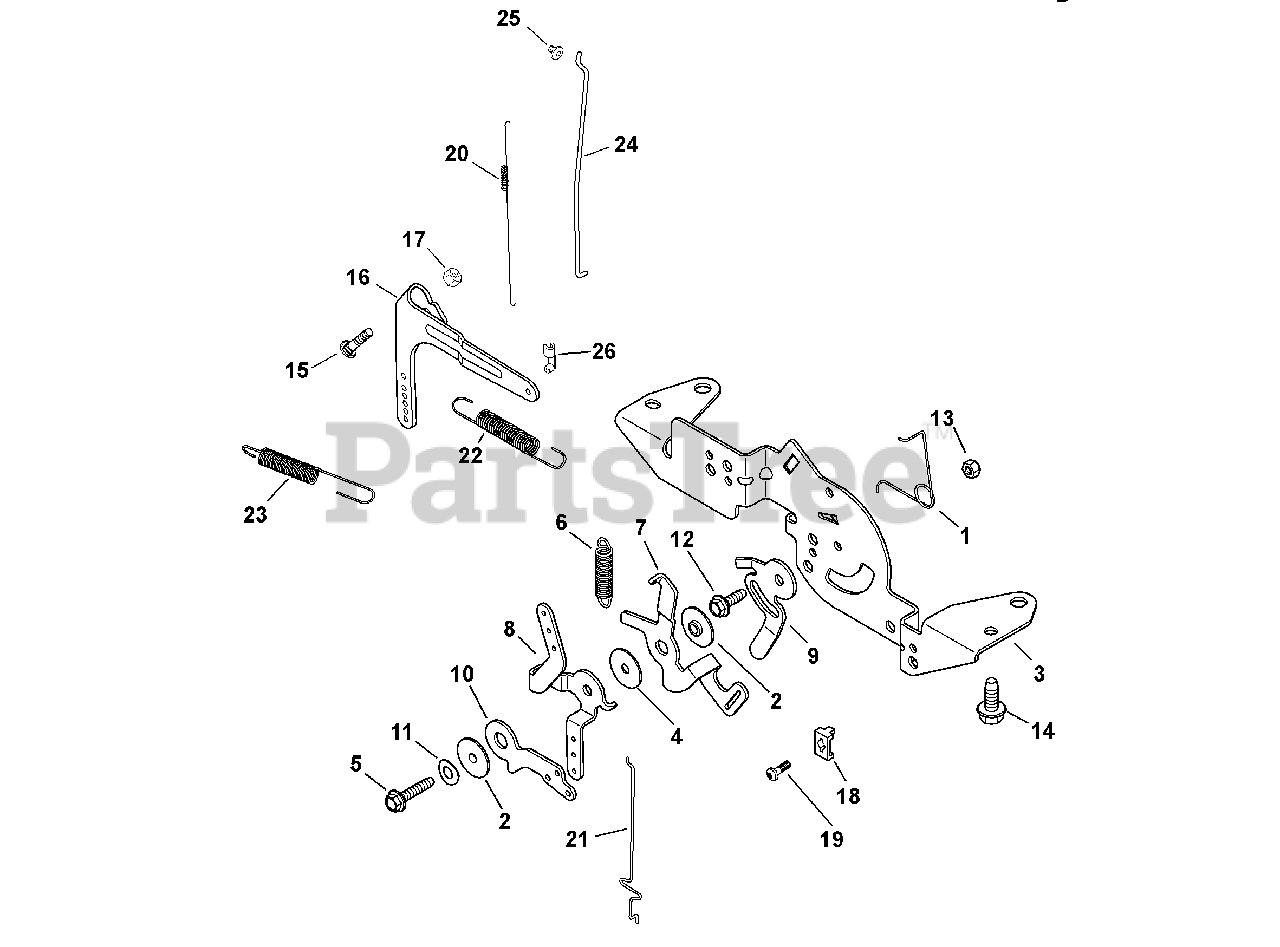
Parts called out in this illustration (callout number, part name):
1	Choke Return Spring
3	Control Bracket
4	Flat Washer, 5.5mm
5	Screw, M5 x 0.8 x 25mm
6	Speed Control Spring
7	Governor Spring Lever
8	Speed Control Lever
9	Speed Setting Lever
10	Choke Lever
11	Spring Washer, 1/4
12	Flange Screw, M5 x .8 x 16
13	Lock Nut, M5 x 8
14	Flange Screw, M6 x 1.0 x 16
15	Bolt, M6 x 1.0 x 25
16	Governor Lever
17	Flange Nut, M6 x 1.0
18	Cable Clamp
19	Screw, M5 x .8 x 16
20	Linkage Spring
21	Choke Linkage
22	Governor Spring
23	Governor Spring
24	Throttle Linkage
25	Linkage Retaining Bushing
26	Throttle Linkage Bushing
